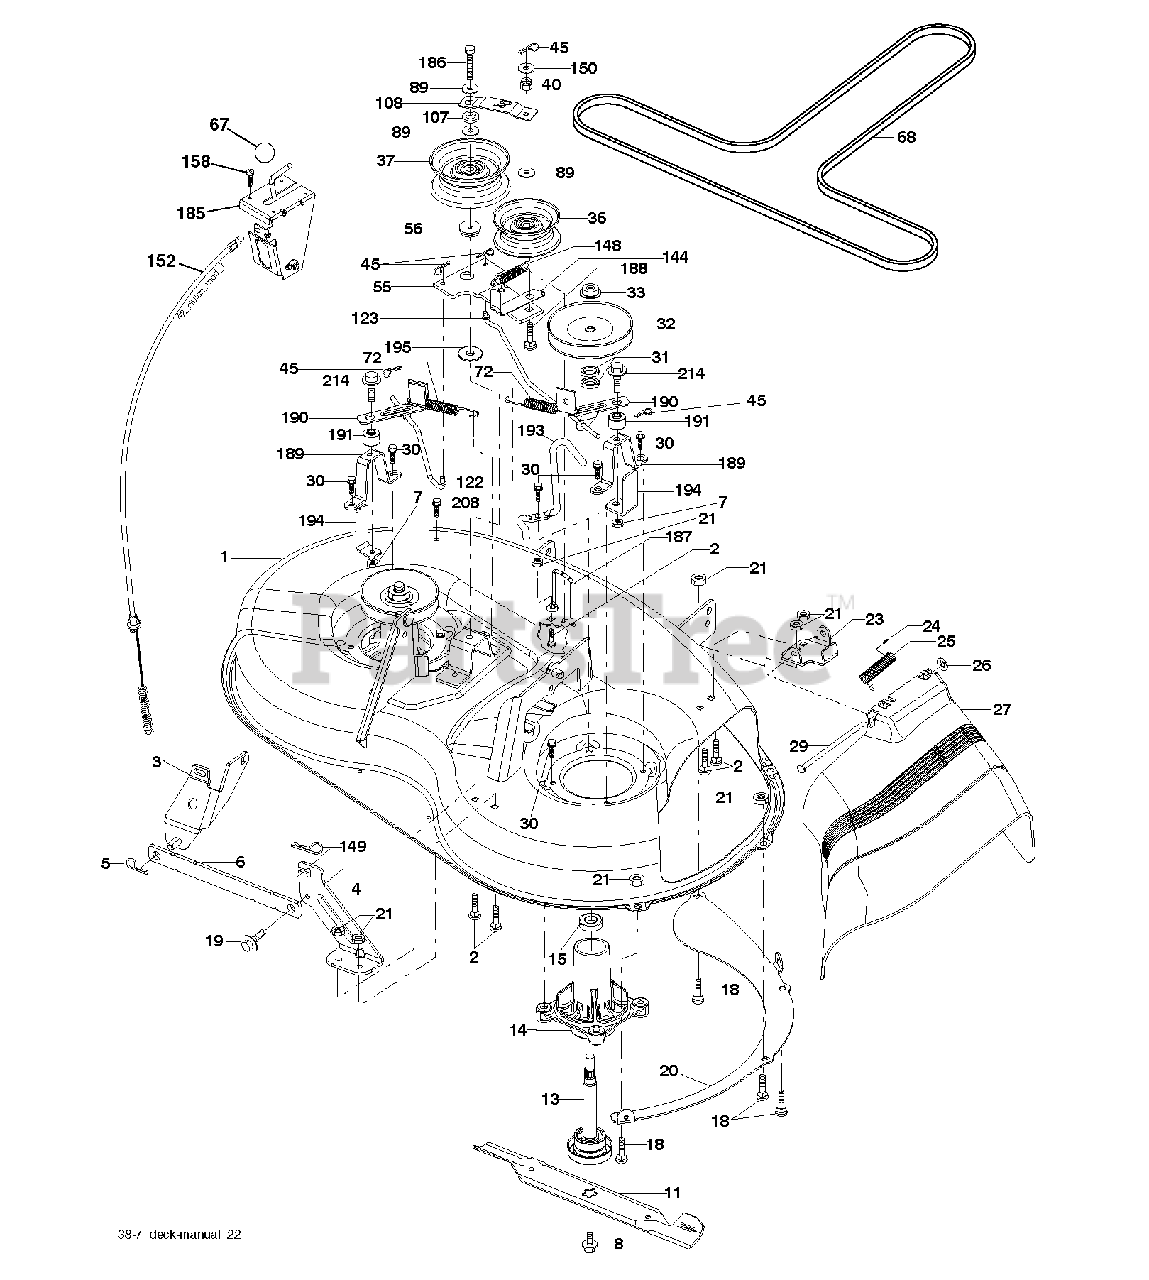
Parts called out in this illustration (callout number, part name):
1	DECK.WELDMENT.38"2005
2	BOLT
3	BRKT ASM SWAY BAR
4	BRACKET DECK SWAY BAR 38"/42"
5	RETAINER-SPRNG RB
6	BAR SWAY DECK
7	NUT.71038.31-18.HEX.NYLOCK
8	BOLT.WASHER.ASM.7/16-2
11	BLADE 38" PREMIUM
13	SHAFT.ASM.MDRL.N/GREASE.38
14	HOUSING MANDREL
18	BOLT
19	BOLT SHD 5/16-18
20	BAFFLE VORTEX
21	LOCKNUT
23	BRKT.DEFLECTOR.38"2005+
24	CAP-SLEEVE LT
25	SPRING.TORSION.DEFLECT
27	Deflector Shield, 38-7/97cm
29	ROD.HINGE
30	SCREW, WASHER HEAD
31	WASHER.SPACER.MANDREL
32	PULLEY MANDREL
33	NUT.FLANGE.LOCK.TOP
36	FLAT IDLER PULLEY
37	PULLEY.IDLER.FLAT.UNPLATED
40	LOCKNUT
45	RETAINER M
56	SPACER.RETAINER.MOWER
67	KNOB T (3/8 HOLE)
68	V-BELT.MOWER.38"2005+
72	SPRING.BRAKE.RETURN.38"
89	WASHER
107	SPACER.IDLER.ARM
108	STIFFENER.IDLER.ARM
122	ROD, BRAKE LH LINK
123	LINK.BRAKE.38"RIGHT
148	IDLER RETURN SPRING
149	SPRING.RETAINER.YELLOW.ZINC
150	WASHER LT
152	CABLE.CLUTCH.38".SERVICE
158	SCREW
185	HEAD ASM. CABLE CLUTCH
186	SCREW.HXWSH.3/8
188	BOLT, CARRIAGE IDLER
189	STAND, BRAKE
190	ARM, BRAKE
191	SPACER, BRAKE
193	KEEPER BELT RH MANDREL
194	GUARD BRAKE
195	WASHER 12/32X2X10GA
208	SCREW 3/8-16X1/2
214	BOLT/WASHER ASM 5/16-18
